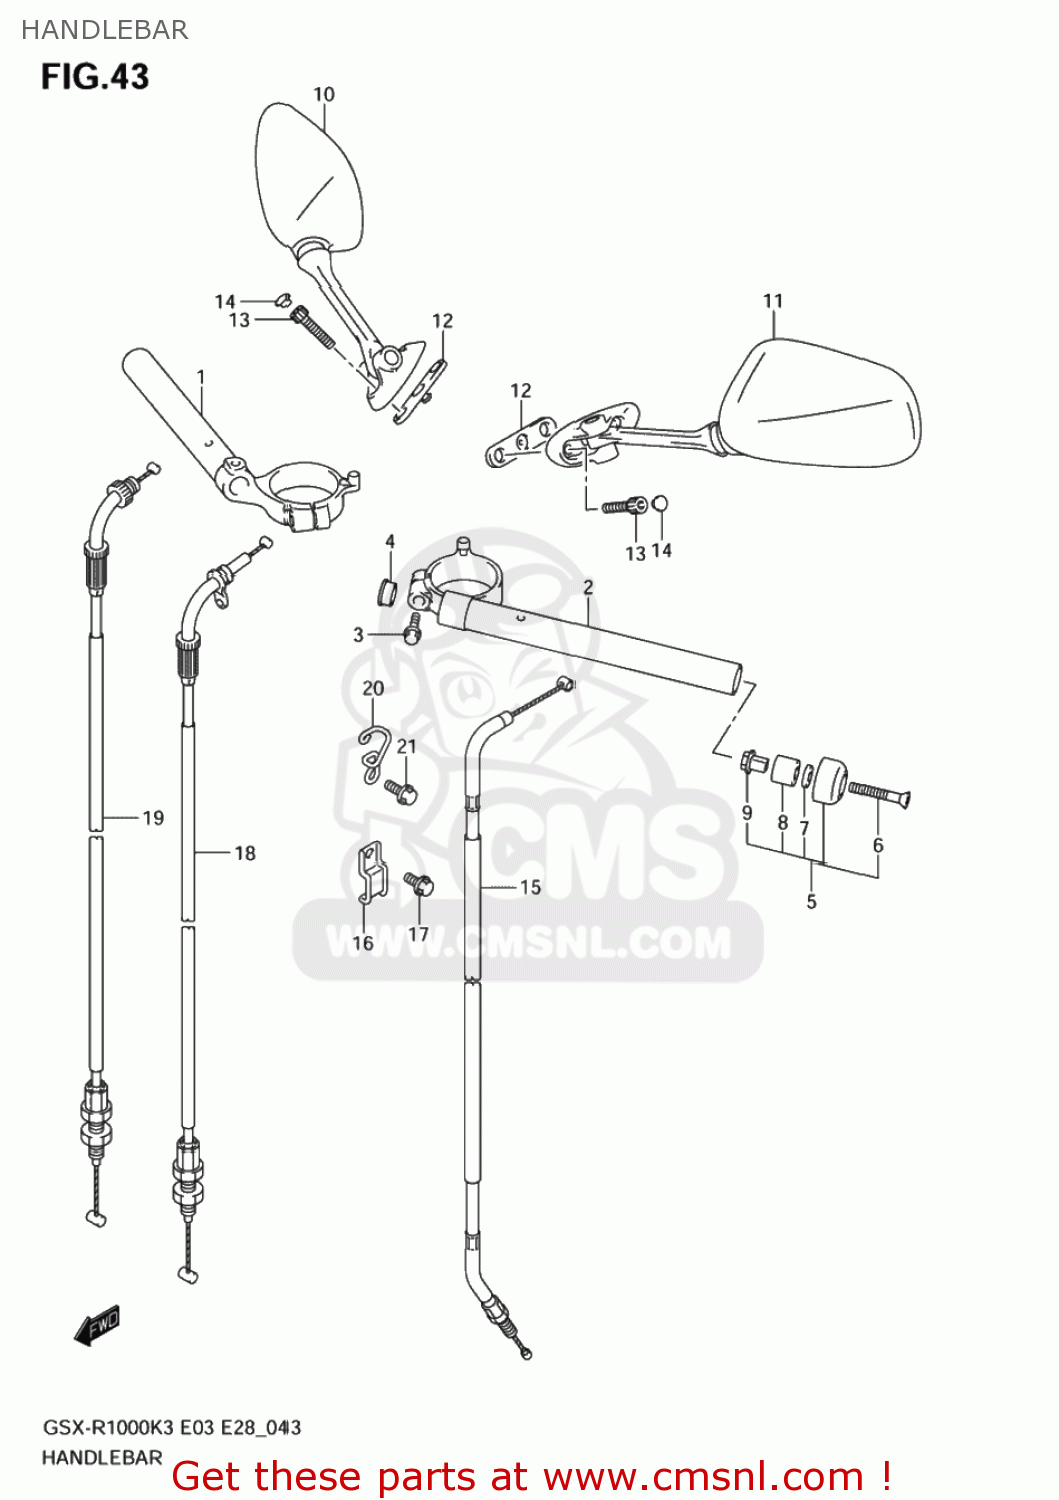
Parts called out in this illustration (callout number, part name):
1	HANDLEBAR,R
2	HANDLEBAR,L
3	BOLT,HANDLEBAR
4	PLUG(OD:17)
5	BALANCER SET,H
6	SCREW
7	WASHER(6.5X16X4)
8	EXPANDER,HANDLE BALANCER
9	NUT,HANDLE BAL
10	MIRROR ASSY,RE
11	MIRROR ASSY,RE
12	CUSHION,RR VIEW MIRRORR
13	BOLT
14	CAP(OD:10)
15	CABLE ASSY,CLUTCH
16	GUIDE,THROTTLE CABLE
17	BOLT
18	CABLE ASSY,THROTTLE NO.1
19	CABLE ASSY,THROTTLE NO.2
20	GUIDE,THROTTLE CABLE
21	BOLT
